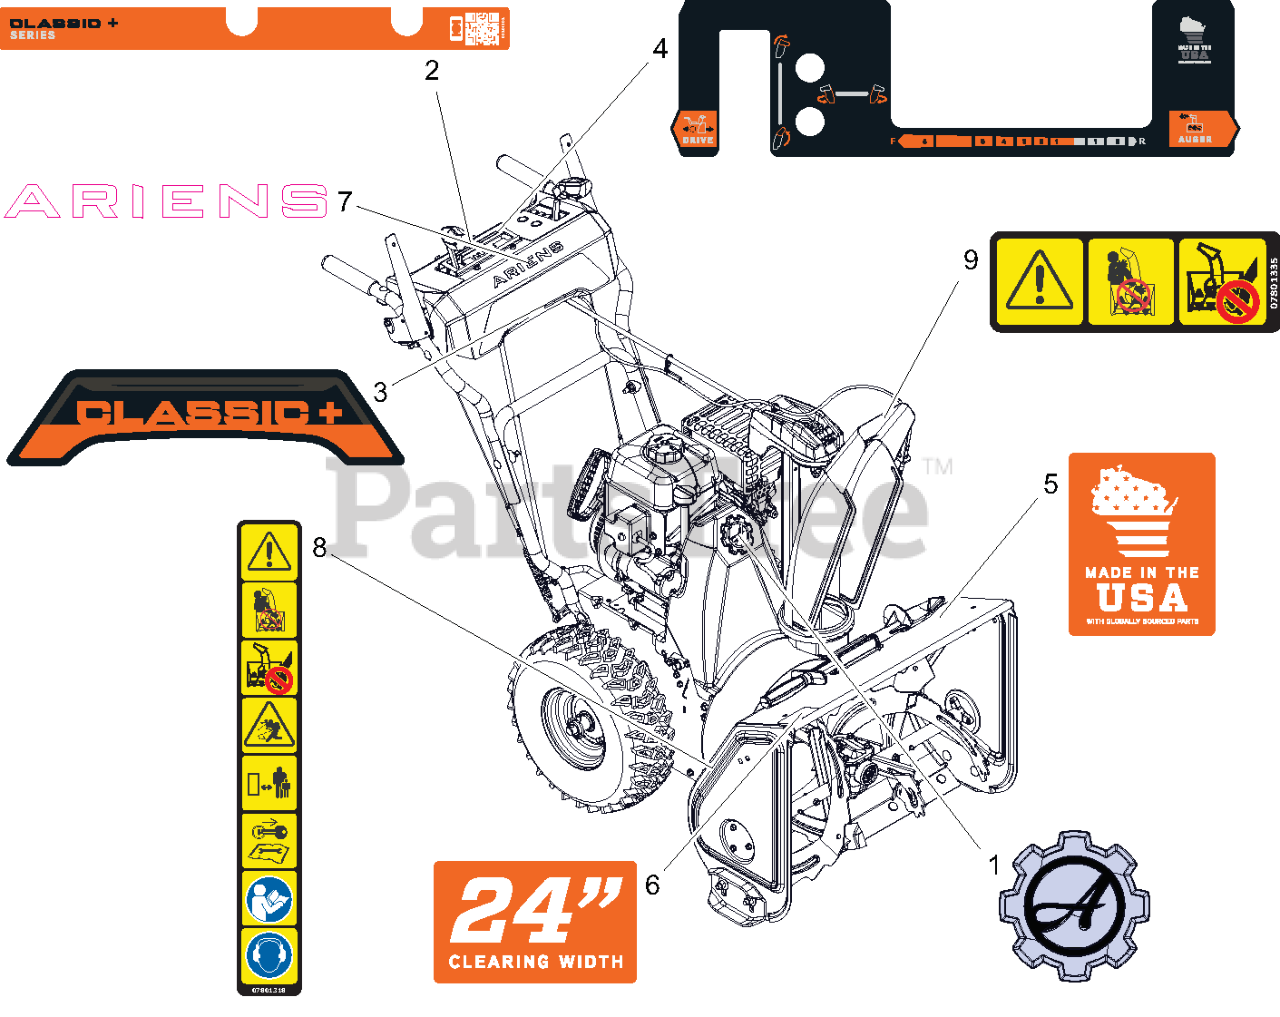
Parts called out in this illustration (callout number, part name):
1	DECAL, ARIENS - GEAR BADGE
2	DECAL- DASH - CLASSIC PLUS
3	DECAL- BEZEL - CLASSIC PLUS
4	DASH- CONTROL - SMALL DASH
5	DECAL- MADE IN USA
6	DECAL- CLEARING - 24
7	DECAL- ARIENS - 7.46"
8	DECAL- SAFETY - DANGER
9	DECAL- DANGER
